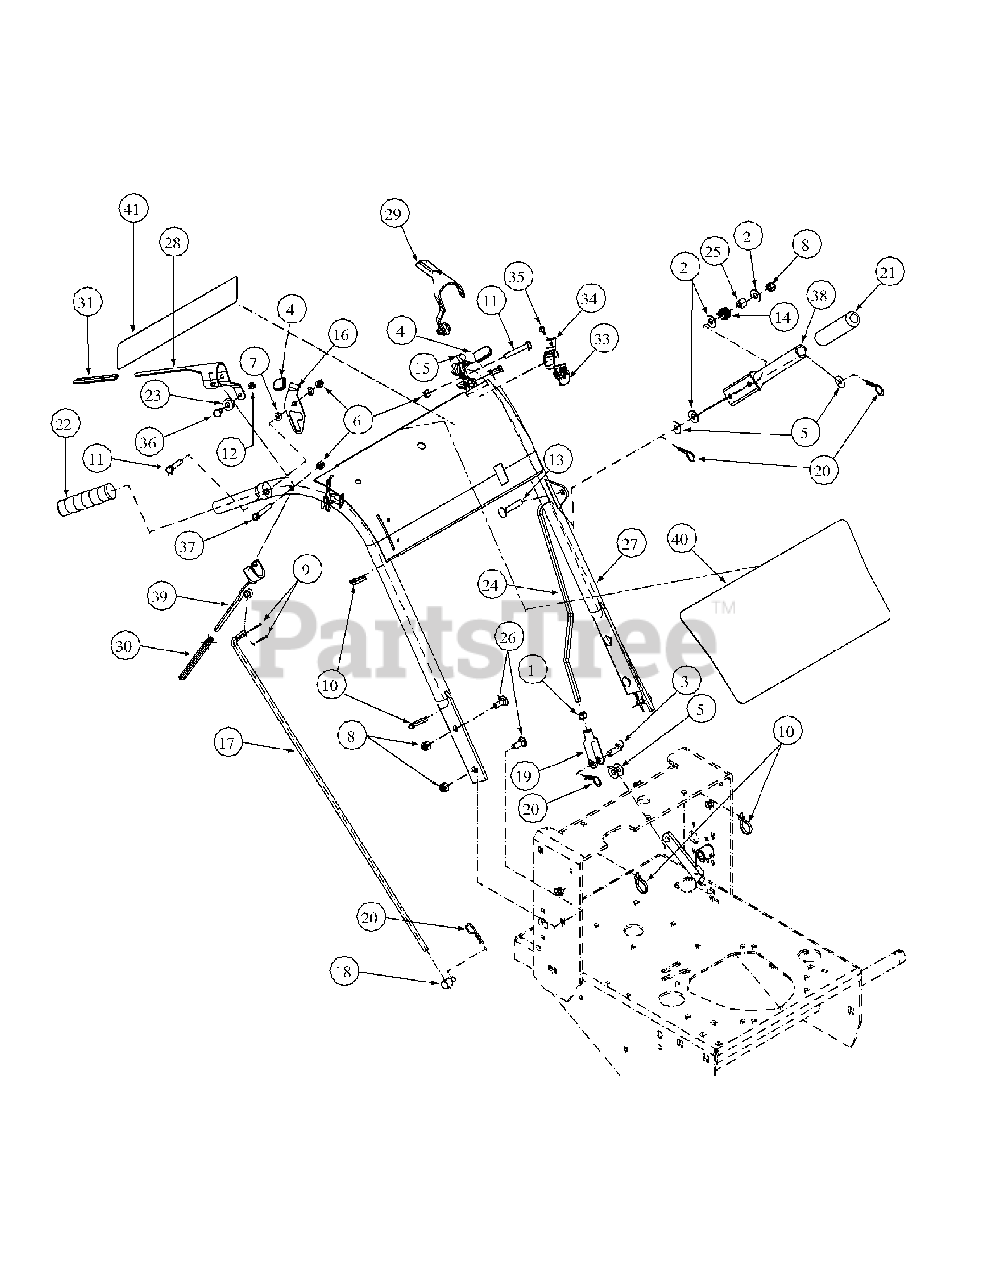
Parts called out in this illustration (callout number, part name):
1	Hex Nut, 3/8-16
2	Flat Washer, 3/8 Zinc
3	Clevis Pin, 3/8 x 1-1/8 Zinc
4	Grip, Neutral Latch, 1.25"
5	Flat Washer, 3/8 Zinc
6	Nylock Nut, 5/16-18
7	Flat Washer, 5/16 Zinc
8	Lock Nut, Nylon Insert, 3/8-16
9	Cotter Pin, 3/32 x 3/4, Zinc
10	Cable Tie, 3/16 x .05 x 7.4
11	Hex Cap Screw, 5/16-18 x 2
12	Lock Nut, Nylon Insert
13	Carriage Bolt, 3/8-16 x 2
14	Spring, .850 OD x 1
15	Neutral Latch, Left Hand
16	Neutral Latch, Right Hand
17	Steering Control Rod
18	Joint Swivel
19	Yoke, 3/8-16 Female
20	Hair Pin 3/8-1/2
21	Handle Grip, Black, 1"
22	Plastic Handle Grip, Black, 4-5/8
23	Control Rod, Hydro Spacer
24	Blade Clutch Rod
25	Spring Sleeve
26	Carriage Bolt, 3/8-16 x 2
27	Handle Assembly
28	Operator Presence Control RH
29	Operator Presence Control LH
30	Control Sleeve, Black
31	Operator Control Sleeve, Yellow
32	Harness Assembly Adapter
33	Switch Mounting Snap
34	Operator Presence Return Spring
35	Hex Index Washer Screw, 0.500
36	Shoulder Screw, .38 x .412, 1/4-28
37	Hex Cap Screw, 5/16-18, 2.00
38	Blade Clutch Lever
39	Lever Assembly Control
40	Label Commercial Mower Panel
41	Label Commercial Mower Instruction
